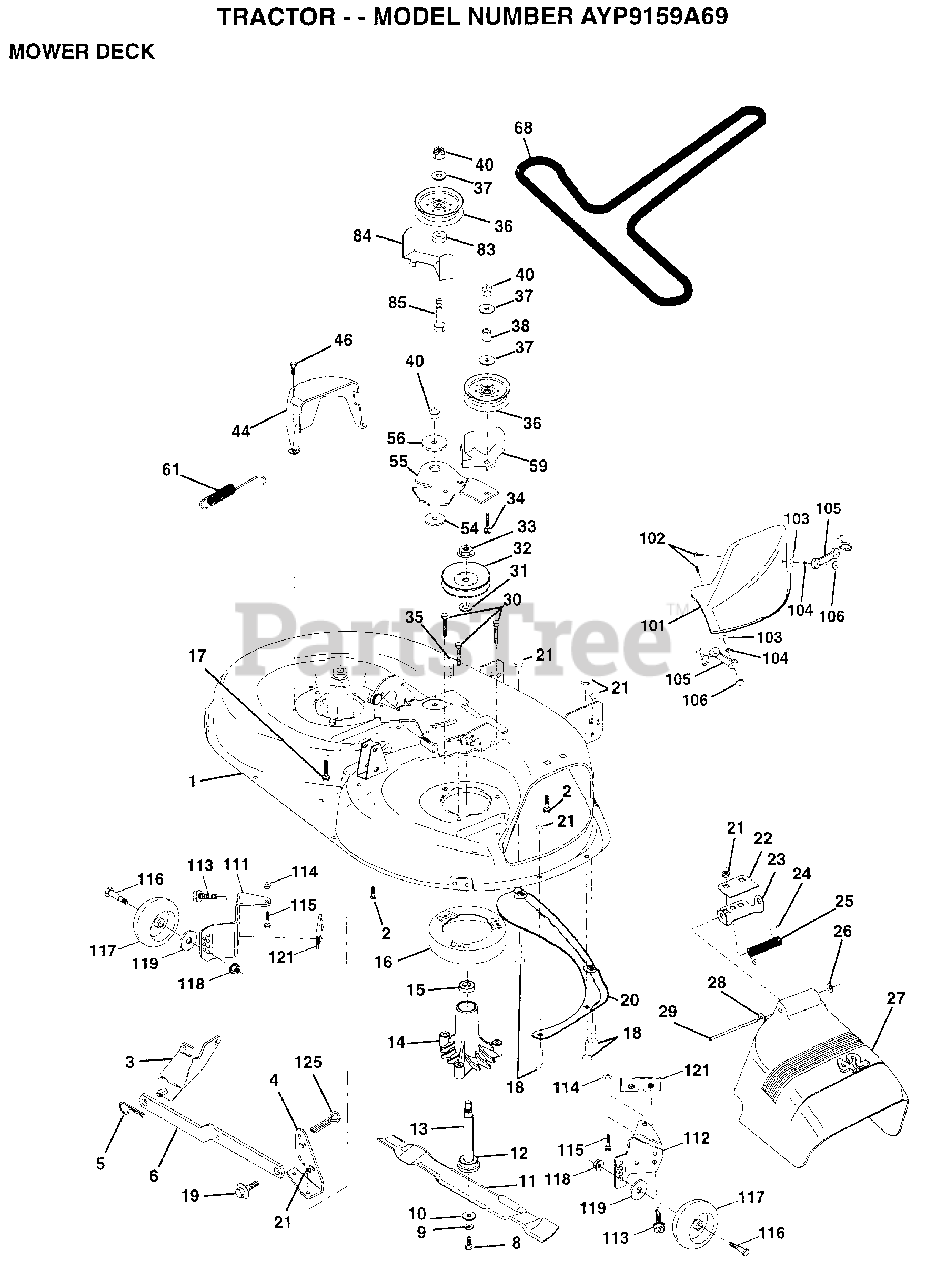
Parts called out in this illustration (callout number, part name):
1	DECK.WELD.42.
2	BOLT
3	BRKT ASM SWAY BAR
4	BRKT DECK SW BAR
8	BLADE BOLT
10	WASHER.HARD.BLADE
11	"BLADE.42"" MULCHER"
12	BEARING.BALL
14	HSG ASM MANDREL
15	BEARING
16	STRIPPER RND MWR
17	BOLT CARRIAGE
18	BOLT
19	BOLT SHD 5/16-18
22	STIFFENER BRKT
23	DEFLECTOR BRKT
24	CAP-SLEEVE LT
25	SPRING TORSION
26	NUT PUSH M
27	DEFLECTOR.SHIELD
28	WASHER
29	HINGE ROD
31	WASHER
34	BOLT
35	XMAS TREE FASTNER
36	FLAT IDLER PULLEY
37	WASHER
44	GUARD MAND LH BLK
46	SCREW.1/4-20X5/8
54	HARDENED WASHER
56	SPACER RETAINER
59	GUARD IDLER TUV
61	SPRING.EXTENSION
68	BELT.V.T-PATH
83	WASHER
85	BOLT RDHD 3/8-16
101	"COVER.MULCH.42"""
102	SCREW
103	WASHER #10
104	LOCKWASHER
106	WELDNUT
113	SCREW
116	BOLT.SHOULDER
117	WHEEL GAGE DONUT
118	LOCKNUT
119	WASHER
121	BRACKET.EXTRD.GWL
125	COTTER PIN
